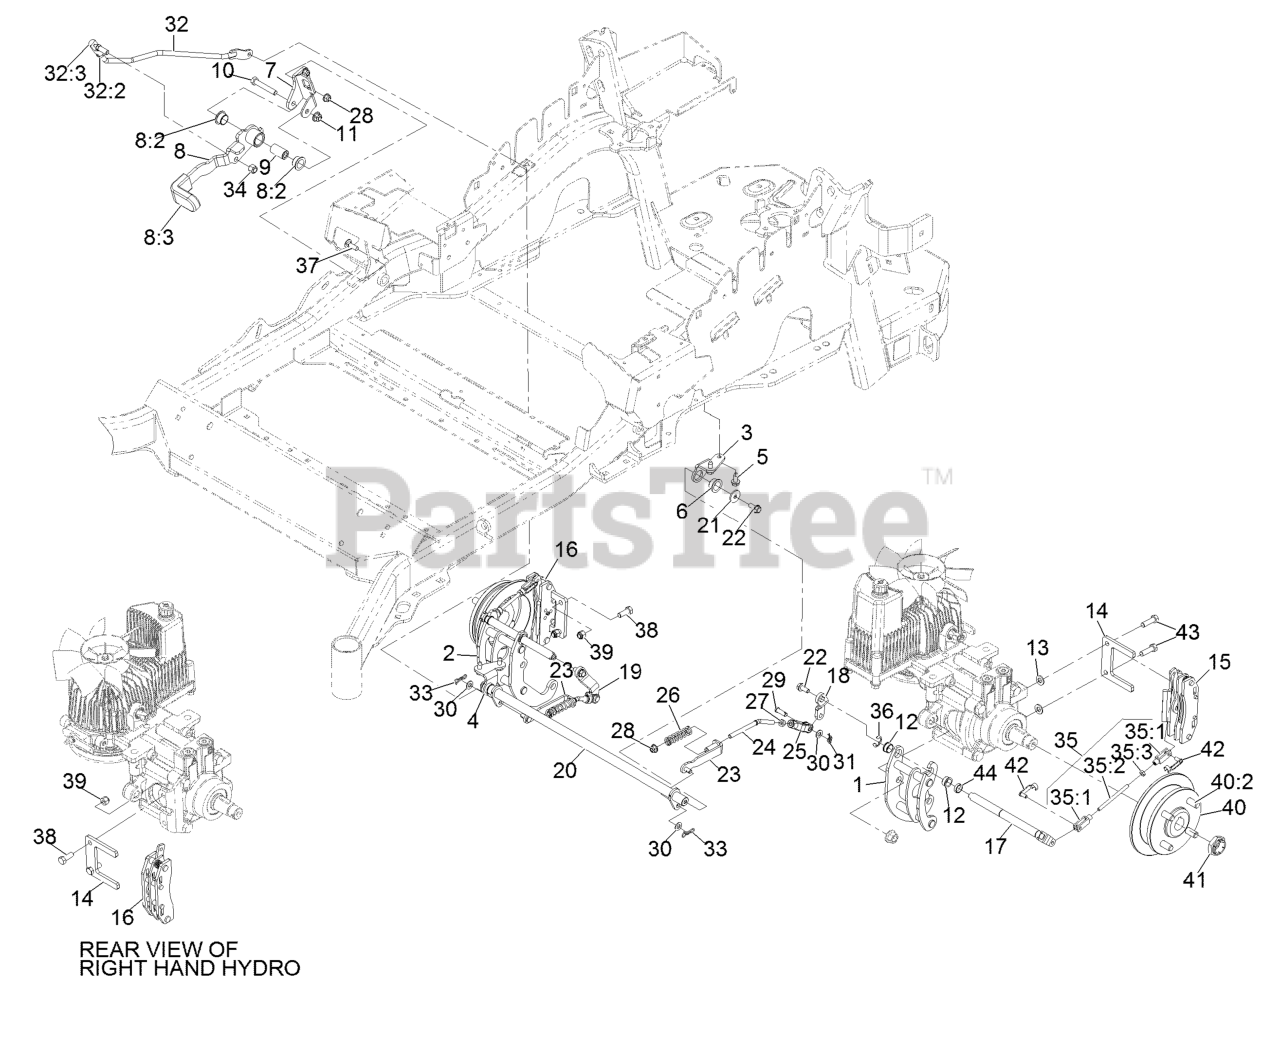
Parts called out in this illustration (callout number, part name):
1	MOUNT-BELLCRANK, LH
2	MOUNT-BELLCRANK, RH
3	MOUNT-PIVOT, LH
4	MOUNT-PIVOT, RH
5	Screw-HWH 5/16-18 X 3/4 Tf
6	BUSHING-FLANGE
7	BRACKET-MOUNT
8	BRAKE LEVER ASM W/ GRIP
8:2	BUSHING-FLANGE
8:3	GRIP-LEVER
9	HANDLE-PIVOT, BRAKE
10	SCREW-HH
11	NUT-HF, NI
12	BUSHING
13	WASHER-FLAT
14	PLATE-MOUNT, BRAKE
15	CALIPER-BRAKE
16	CALIPER-BRAKE, RH
17	BELLCRANK
18	ARM-INNER, LH
19	ARM-INNER, RH
20	SHAFT-CROSS
21	WASHER-FLAT
22	SCREW-HHF
23	BRACKET-L
24	LINKAGE-MID
25	YOKE-OFFSET
26	SPRING-COMPRESSION
27	NUT-JAM
28	NUT-HF, NI
29	PIN-CLEVIS
30	WASHER-PLAIN
31	PIN-COTTER, LOCKING
32	FRONT LINKAGE ASM
32:2	END-TIE ROD, RH
32:3	NUT-HJ
33	PIN-COTTER, LOCKING
34	NUT-LOCK
35	REAR LINKAGE ASM
35:3	NUT-JAM
37	BOLT-CARR
38	SCREW-HH
39	NUT-LOCK, NI
40	WHEEL HUB ASM
40:2	STUD-WHEEL
41	LOCKNUT
42	PIN-CLEVIS, SPRING
43	SCREW-LOCK, PATCH
